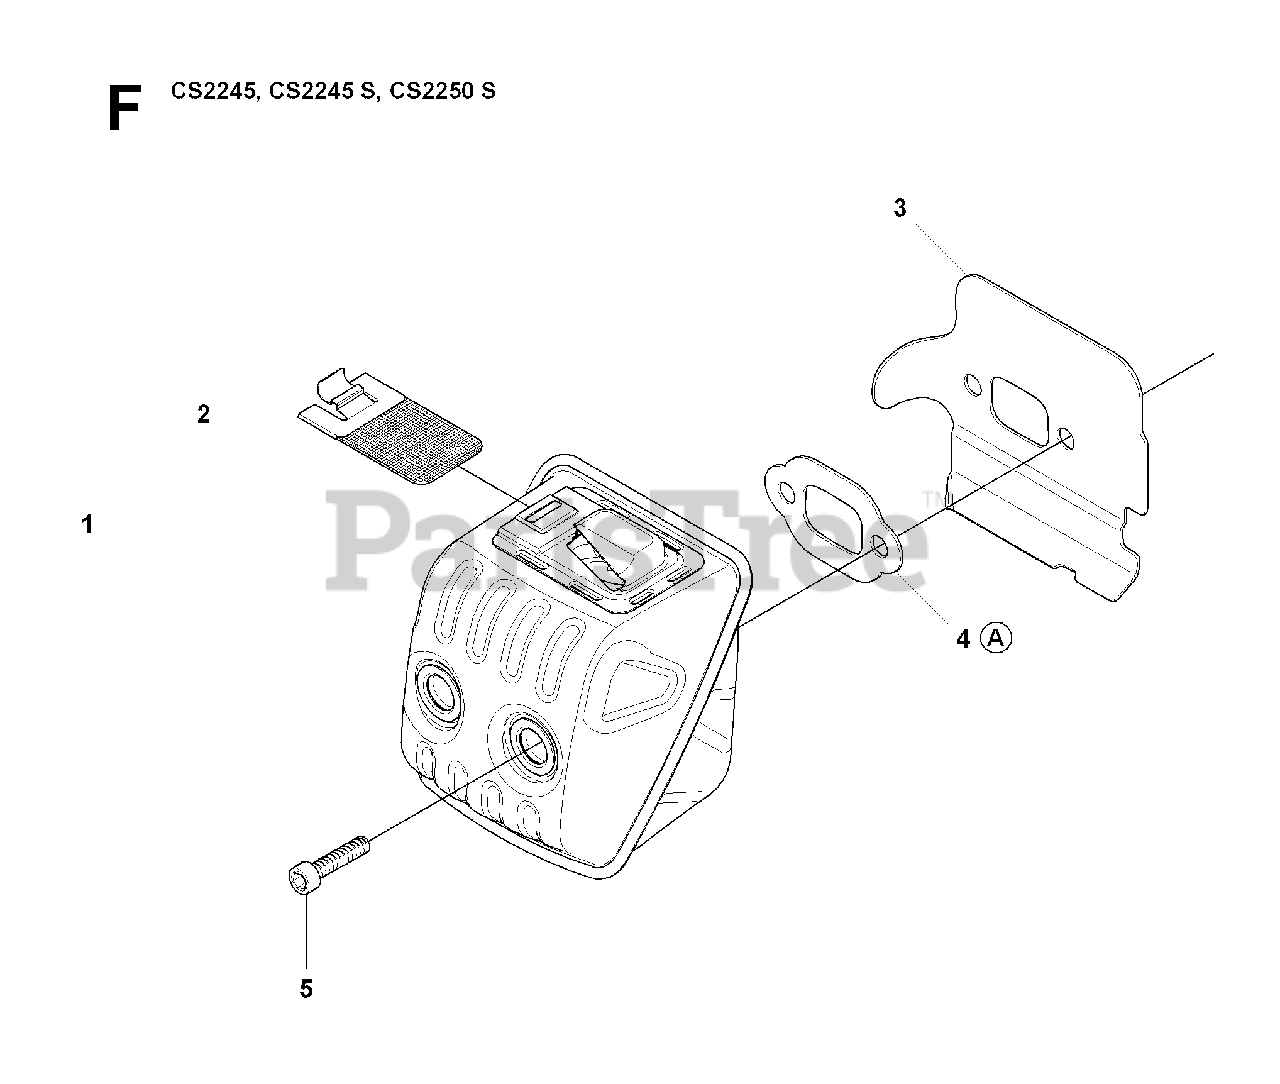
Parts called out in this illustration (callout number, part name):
1	%MUFFLER ASSY
2	SPARK ARRESTER
3	%HEAT DEFLECTOR
5	SCREW MC6S 6X16
